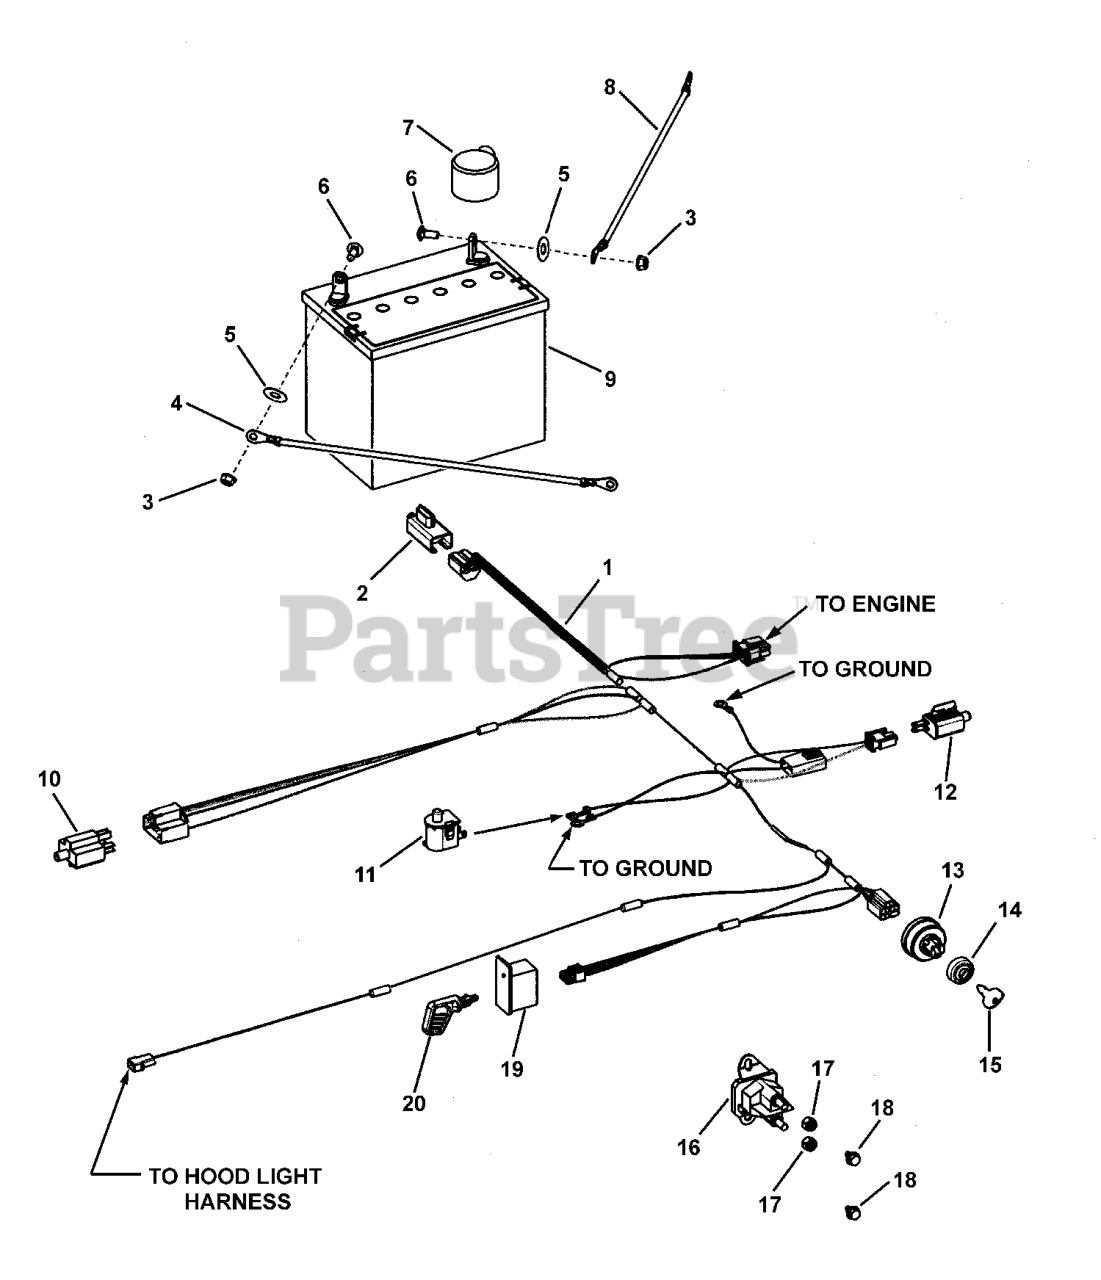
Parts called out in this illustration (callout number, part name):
1	HARNESS, WIRING, GEAR, TCT, MY'08
2	SWITCH, LIMIT, NO/NC, SNAP-IN
3	NUT-HEX 1/4-20 NC-2B YELLOW
4	CABLE-BAT 8GA 12.00L - BLACK
5	LOCKHER 1/4
6	CAPSCREW-HEX HD 1/4-20X0.750 G5 YEL
7	BOOT BATTERY POSITIVE
8	CABLE-BAT 8GA 18.00L - RED
9	BATTERY, 12 VOLT, 230 CCA
10	SWITCH, 3 POLE, PLUNGER, SNAP-IN
11	SWITCH, Seat, Push Button (NC)
12	SWITCH, LIMIT, NO, SNAP-IN
13	SWITCH,IGNITION-AFTERFIRE SOLENOID
14	CAP-IGNITION SWITCH
15	KEY, IGNITION
16	SOLENOID - 3 POLE
17	SCREW 1/4-14X.38"ST-
18	NUT, HEX LOCK 1/4-20 BZ
19	SWITCH, RMO Module Only
20	KEY, RMO Module Plastic
